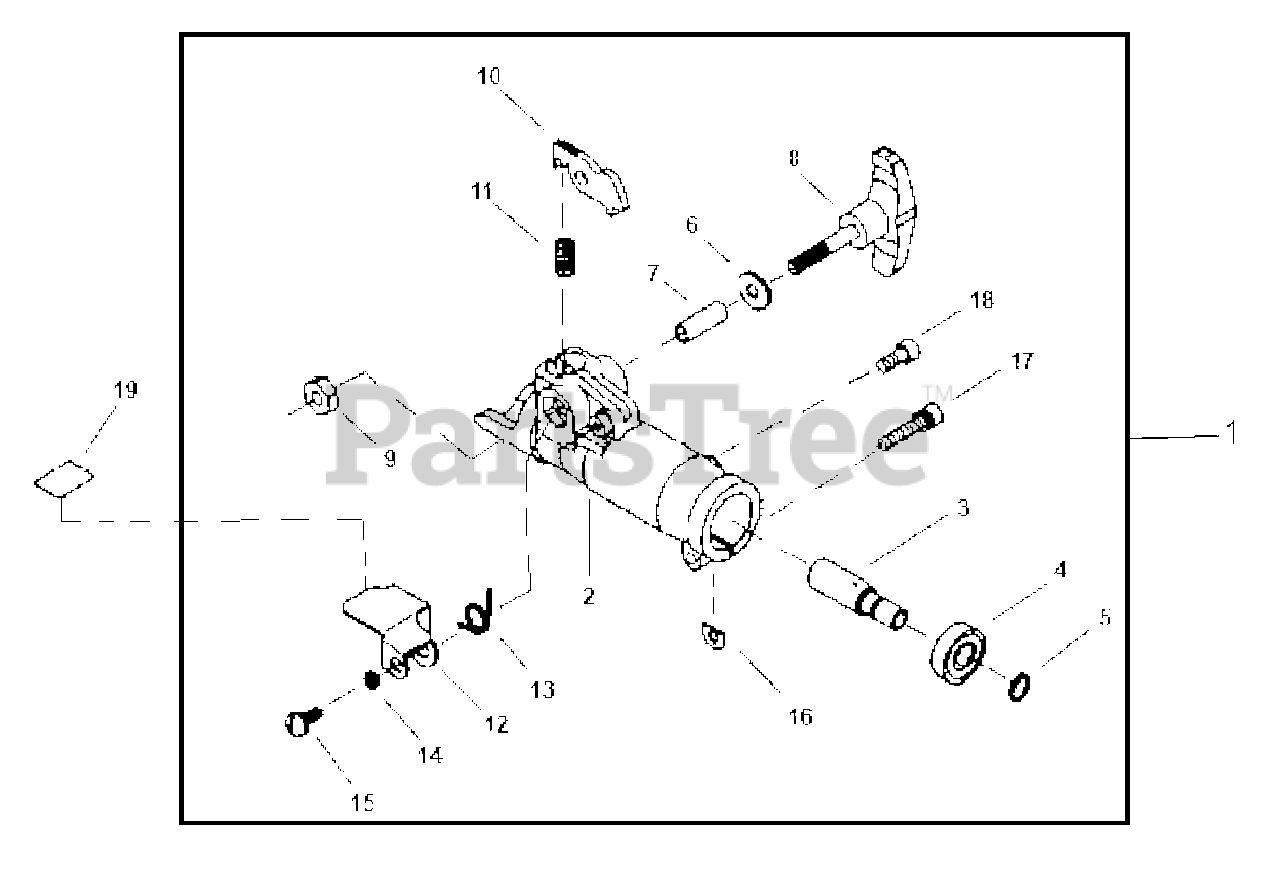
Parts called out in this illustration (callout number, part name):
1	COUPLER ASSY
2	COUPLER
3	CONNECTOR, SHAFT
4	BEARING, BALL - 609ZZ
5	RING, RETAINING
6	WASHER
7	COLLAR
8	KNOB
9	NUT
10	LEVER, LOCK
11	SPRING
12	COVER
13	SPRING
14	COLLAR
15	SCREW - 5X12
16	SHIM
17	SCREW - 5X20
18	SCREW - 5X12
19	LABEL - LATCH INSTRUCTION
